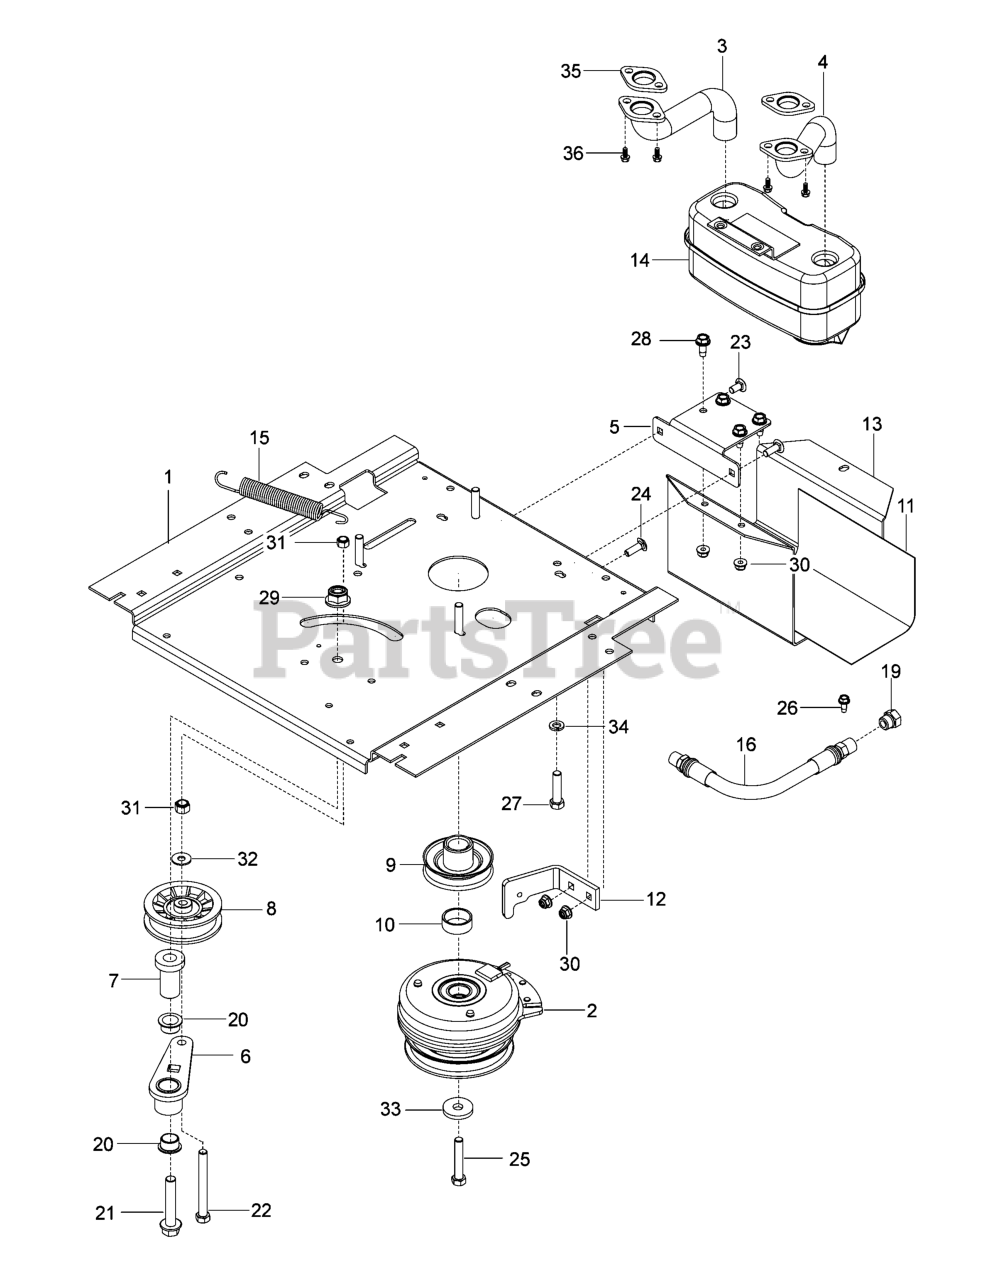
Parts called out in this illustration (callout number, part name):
1	PLATE, Engine
2	CLUTCH ASSEMBLY
3	PIPE-EXHAUST
4	PIPE-EXHAUST
5	BRACKET, Muffler
6	ARM, Idler
8	PULLEY, Idler
9	PULLEY, Crankshaft
10	SPACER, Clutch
11	SHIELD, Muffler
12	BRACKET, Clutch
13	GUARD, Muffler
14	MUFFLER ASSEMBLY
16	HOSE, Oil Drain
19	PLUG, Oil
20	BEARING, Flange
21	CAPSCREW, 1/2-13 X 2-3/4 HEX FLANGE HD
22	CAPSCREW, 3/8-16 X 3-1/2 HEX HD
23	BOLT, 5/16-18 X 3/4 GR. 5 ZD
24	CAPSCREW, 5/16-18 X 1 GR. 5
25	CAPSCREW, 7/16-20 X 2-1/2 HEX HD
26	SCREW,1/4-20 X 5/8 THREAD FORM
27	CAPSCREW, 5/16-18 X 1-1/2 GR. 5
28	SCREW, 5/16-18 x 3/4 Thred Roll
29	LOCKNUT, 1/2-13 HEX FLANGE NYLOC
30	LOCKNUT, 5/16-18 HEX FLANGE NYLOC
31	LOCKNUT, 3/8-16 HEX NYLOC
32	Washer 13/32 x 7/8 x 14 Ga.
33	Washer 1-1/2 OD x 15/32 ID x .250
34	WASHER, Locking, 3/8
36	Screw Socket HD 5/16-18 x 1
